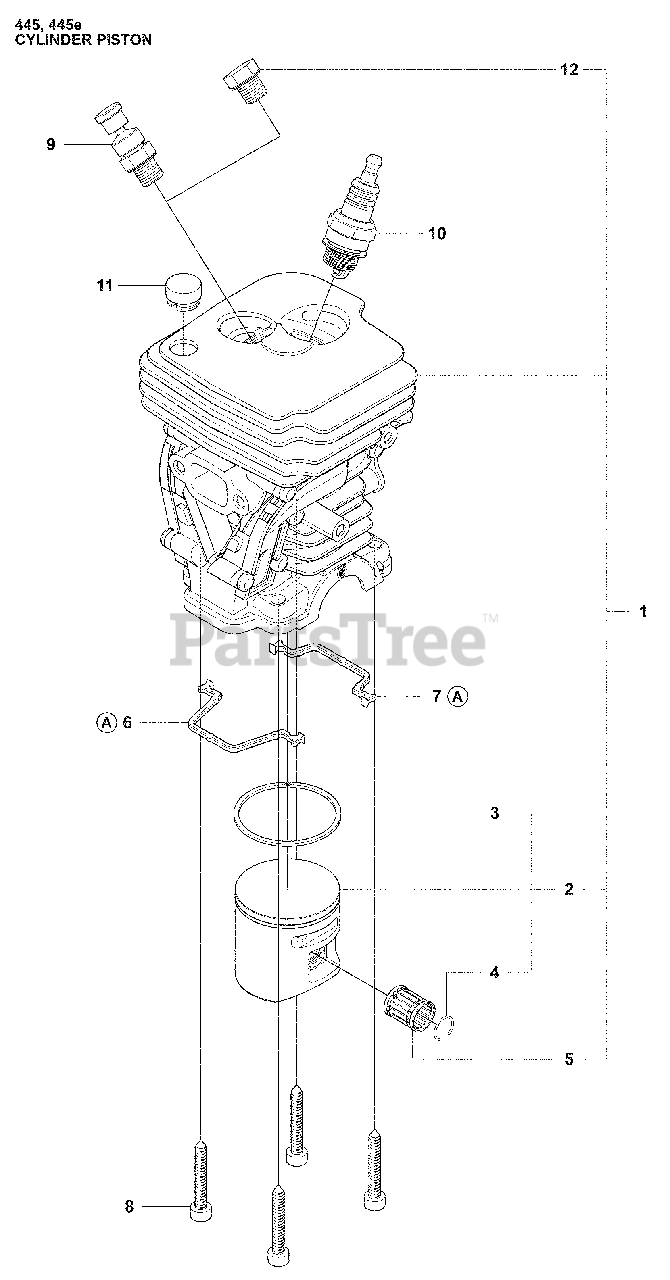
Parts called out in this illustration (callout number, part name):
2	Piston Assembly
3	Piston Ring
4	Circlip, 10mm
5	Support Bushing
9	Decompression Valve
10	Solid Spark Plug, BPMR7A
12	Cylinder Plug
